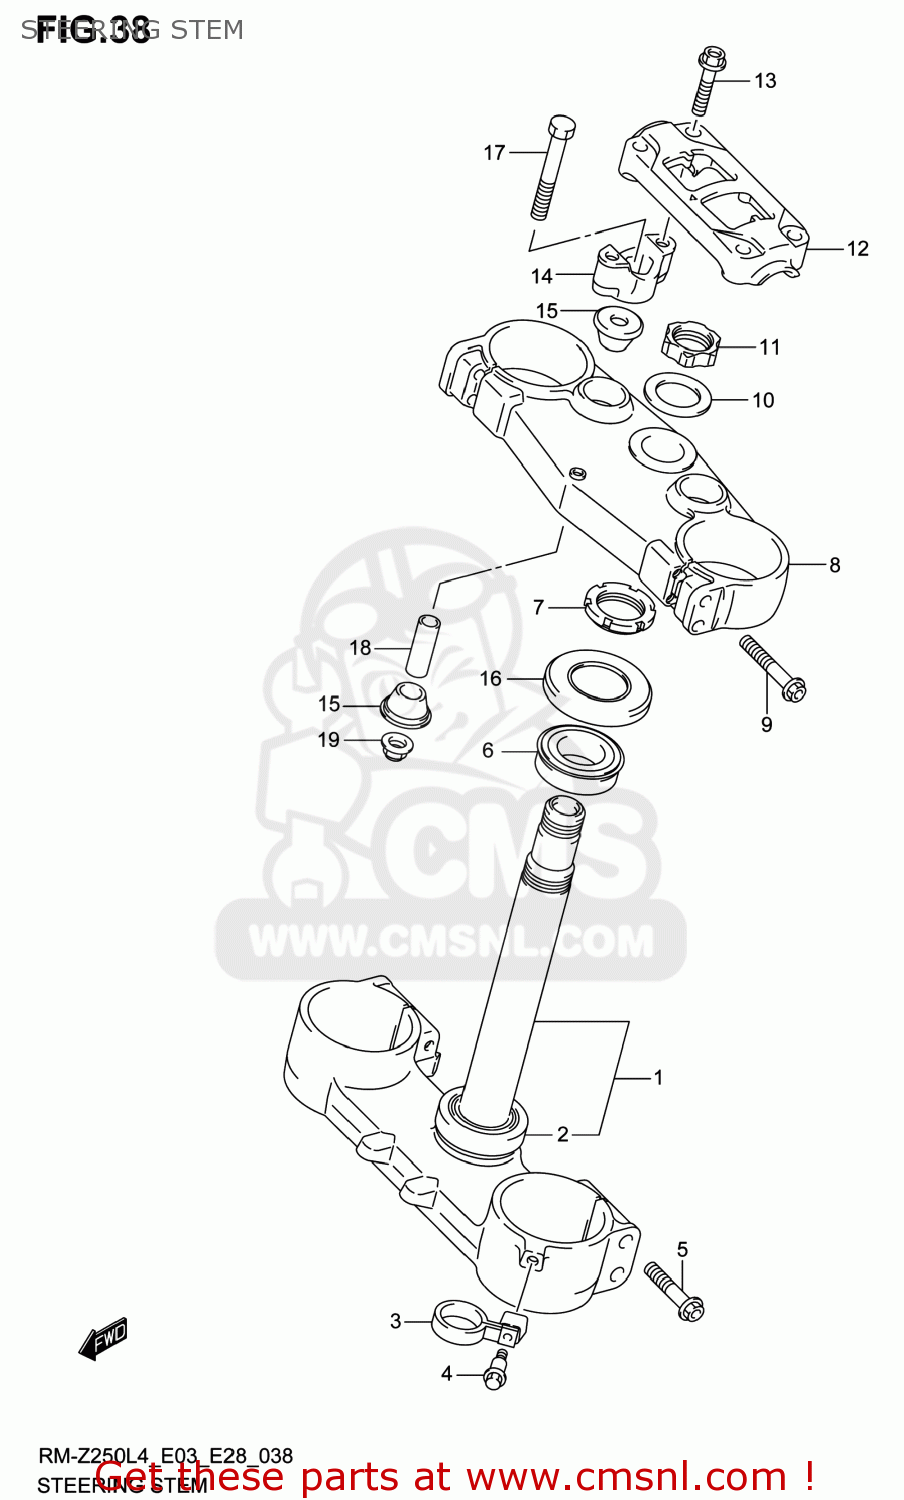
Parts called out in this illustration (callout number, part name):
1	STEM,STEERING
2	BEARING(30X52X16)
3	GUIDE,FR BRAKE HOSE
4	BOLT(6X20.5)
5	BOLT
6	BEARING(30X52X16)
7	NUT,STEERING
8	HEAD,STEERING STEM
9	BOLT
10	WASHER,STEM HEAD
11	NUT,STEM HEAD
12	HOLDER,HANDLE
13	BOLT
14	HOLDER,HANDLE
15	CUSHION,RUBBER
16	COVER,STEERING UPR
17	BOLT,HANDLE HOLDER
18	SPACER
19	NUT
